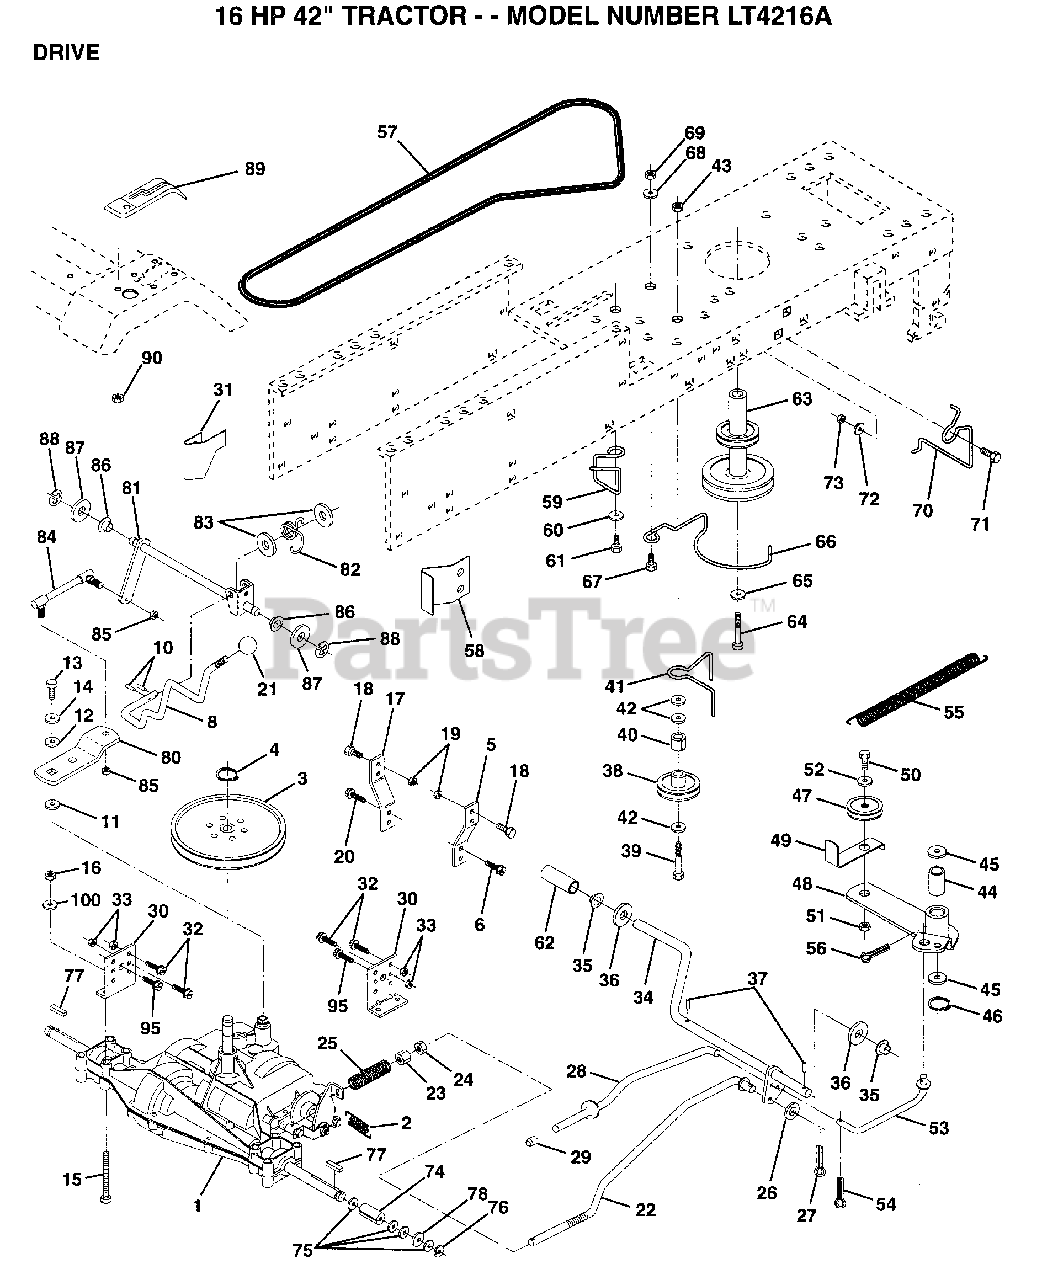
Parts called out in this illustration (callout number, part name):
3	PULLEY TRANS
5	STRAP TORQUE
6	SCREW
8	ROD SHIFT FEND LT
10	PIN COTTER 1/8
11	WASH-SHFT PLT LT
12	WASHER
14	LOCKWASHER
15	BOLT HEX
16	NUT
17	STRAP TORQUE
18	BOLT
19	NUT
20	SCREW
21	KNOB T (1/2-HOLE)
22	BRAKE ROD
23	NUT
24	NUT
25	SPRING ROD LT
26	WASHER
27	COTTER PIN
28	ROD PARK BRAKE
29	PLUNGER CAP T
30	TRANSAXLE MTG BKT
31	"KEEPER,BELT LH T"
32	BOLT
33	NUT
35	NYLON BEARING
36	WASHER LT
38	PULLEY.IDLER.FLAT
39	BOLT
40	SPACER T
41	BELT KEEPER LT
42	WASHER
43	NUT
44	"LY, BEARING"
45	WASHER LT
46	KLIP RING
48	ARM IDLER
49	RETAIN BELT
52	WASHER
53	"LINK, CLUTCH T"
54	COTTER PIN
55	"SPRING, RETURN LT"
56	COTTER PIN
58	"KEEPER,BELT RH T"
59	KEEPER BELT CNTSP
60	WASHER
61	SCREW
62	PEDAL COVER T
63	PULLEY.ENGINE
64	BOLT
65	LOCKWASHER
66	KEEPER.BELT.ENG.L
67	BOLT
68	WASHER
70	KEEPER BELT ENG
71	BOLT
72	WASHER
74	SPACER LT
75	WASHER
76	E-RING LT
77	SQUARE KEY
78	WASHER
80	ARM SHIFT TRANS
81	SHAFT ASM.SHIFT
82	"SPRING,TORSION"
83	WASHER
84	TIE ROD
85	NUT 1/4-28
86	BUSHING
87	WASHER D
88	KLIP RING
90	NUT
95	SCREW
100	WASHER M
